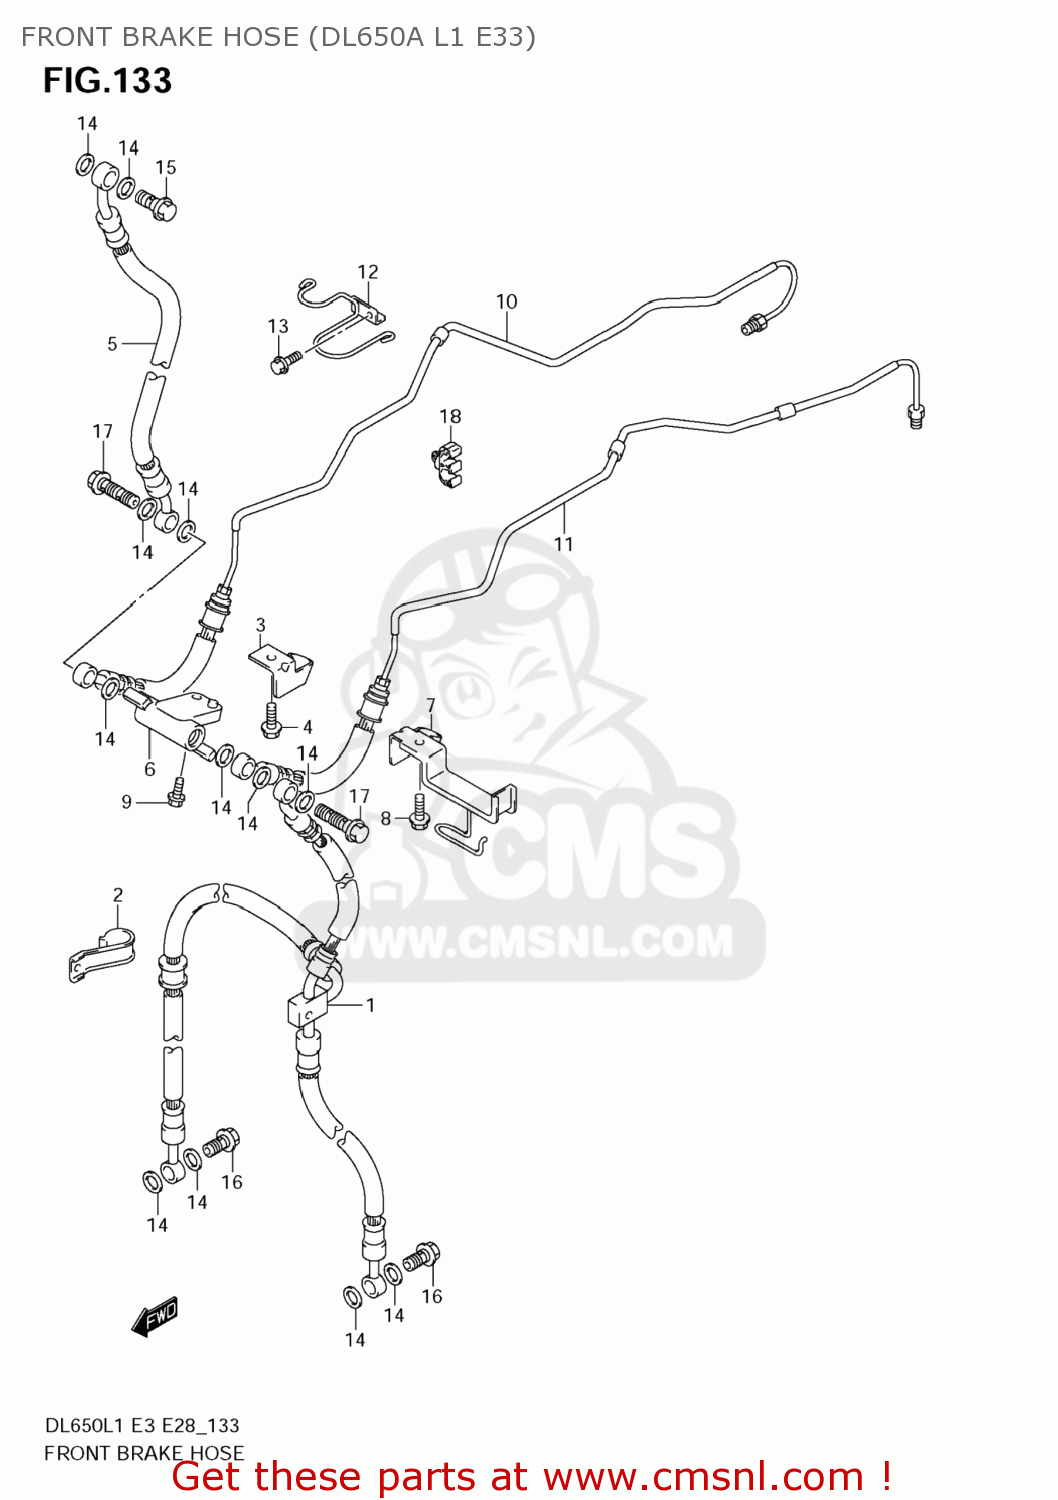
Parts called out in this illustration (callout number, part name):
1	HOSE,FR BRAKE NO.2
2	CLAMP,FR BRAKE HOSE,R
3	CLAMP,FR BRAKE HOSE ASSY NO.1
4	BOLT
5	HOSE,FR BRAKE NO.1
6	JOINT,FR BRAKE HOSE
7	CLAMP,FR BRAKE HOSE NO.2
8	BOLT
9	BOLT
10	HOSE ASSY,FR BRAKE NO.1
11	HOSE ASSY,FR BRAKE NO.2
12	GUIDE,FR BRAKE HOSE
13	BOLT
14	WASHER(10X15X1.5)
15	BOLT UNION
16	BOLT UNION
17	BOLT UNION
18	CLAMP
